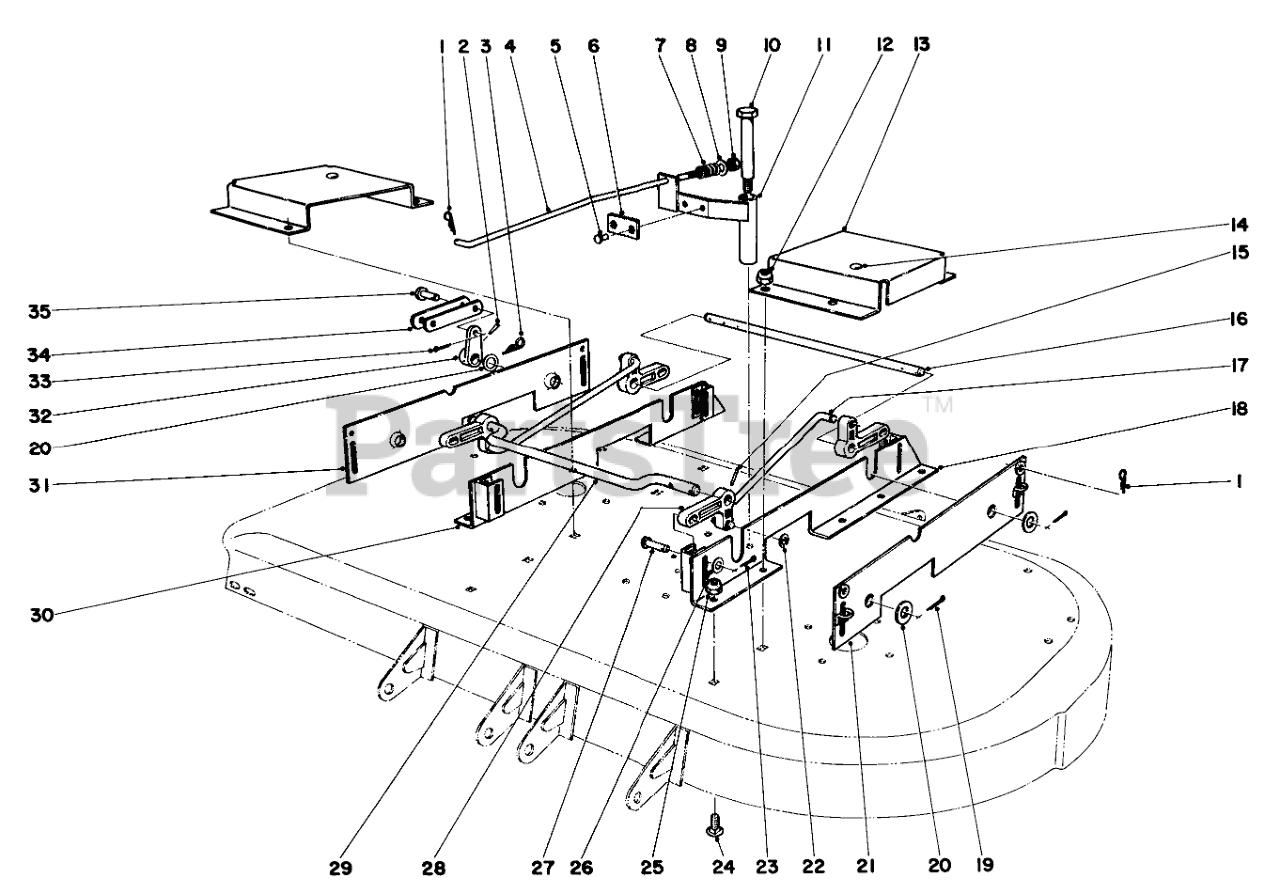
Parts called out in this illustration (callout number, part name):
1	Hair Pin Cotter
2	Pin Drive
3	HAIRPIN COTTER
4	Brake Rod
5	Rivet
6	BLADE BRAKE LINING
7	Spring
8	Washer
10	Shoulder Bolt
11	a. Bracket
12	Nut
13	Cover
14	Plug Button
16	Rear Pivot Shaft
17	Lift Link
18	Bracket Assy. Lower
19	PIN-COTTER
20	Washer
21	Mower Plate Housing
22	RING-RETAINING, EXT
23	PIN-COTTER
24	Screw
25	Nut
26	Washer
27	Lift Pin
28	Bell Crank
29	Front Pivot Shaft
30	Bracket Assy. Lower
31	Mower Plate Housing
32	Lever
33	PIN-COTTER
34	Adjusting Link
35	Pin
